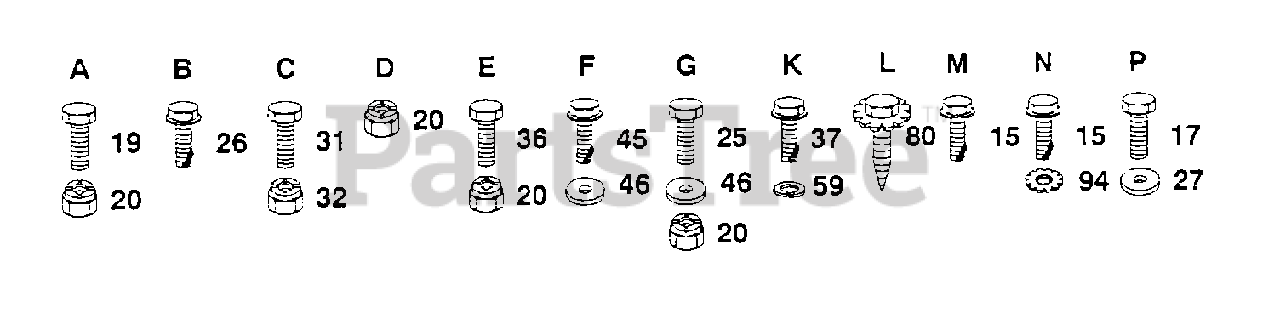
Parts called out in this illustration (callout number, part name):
15	SCREW
17	"BOLT,HEX"
19	BOLT
25	BOLT
26	SCREW
31	BOLT
37	BOLT
45	SCREW
46	WASHER
59	LOCKWASHER
